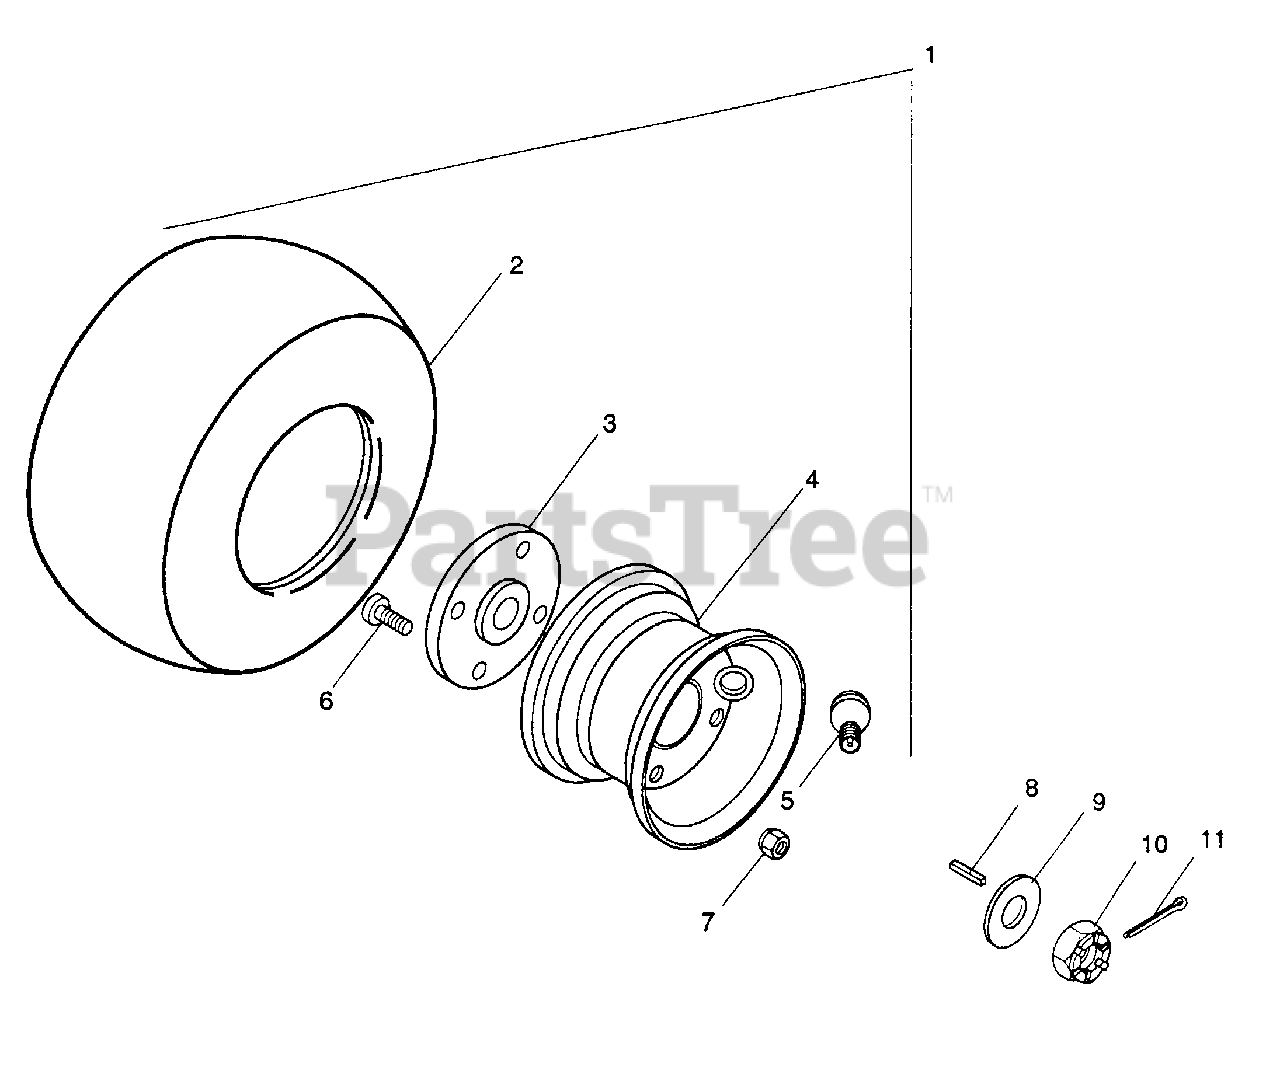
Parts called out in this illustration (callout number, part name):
1	Wheel Assembly 18 x 8.50 - 8
2	Tire/Wheel Assembly 18 x 8.50 - 8
3	Assembly, Hub
4	Assembly, Rim
5	Valve Stem Assembly
6	Bolt, 1/2-20 x 1.25 Pan Head
7	Nut-Hex .50-20
8	Key, Square 3/16 x .750
9	Washer, Flat-Steel .813 x 1.370 x .100
10	Nut, Hex 3/4-28 Slotted
11	Pin-Cotter .06 x 1.00
